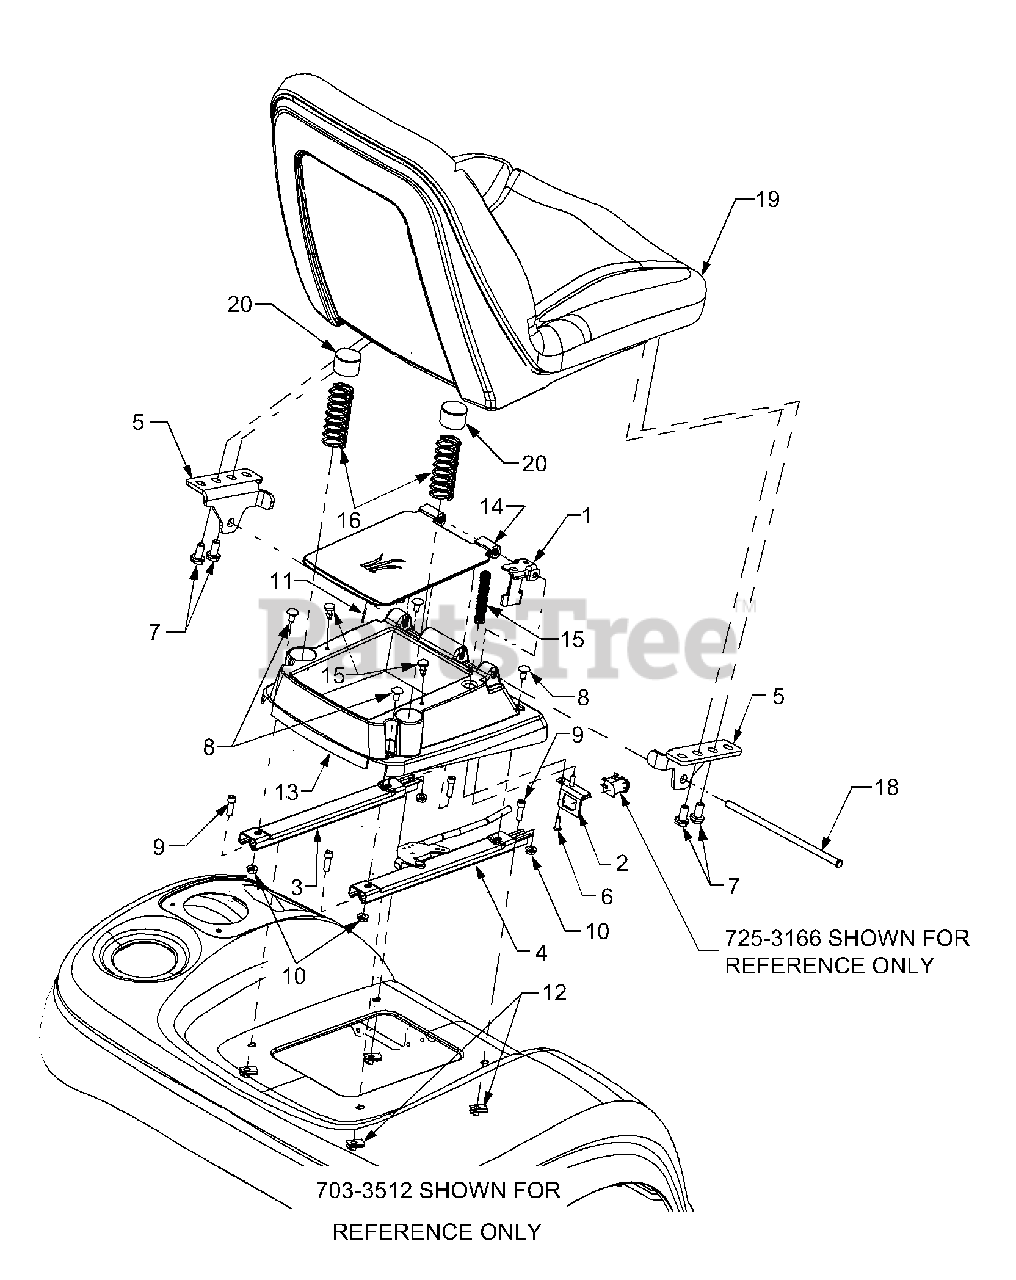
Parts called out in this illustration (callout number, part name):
1	Bracket, Seat Switch
2	Bracket, Switch Mounting
3	Track, Seat, w/o Latch
4	Track, Seat, w/Latch
7	Screw, Hex Wash. Hd. 5/16-18 x .625
8	Carriage Bolt, 5/16-18 x .62
9	Screw, Pan Torx Hd. 5/16-18 x 1.0
10	Nut, Hex Flange Lock, 5/16-18
11	Pin, Cotter, 3/32 x .75
12	Speed Nut, U-Type, 5/16-18
13	Base, Seat
14	Lid, Tlbx
15	Spring, Compression
16	Spring, Compression
17	Bumper
18	Rod, Seat Pivot
19	Seat, High Back
20	Cap, Spring
